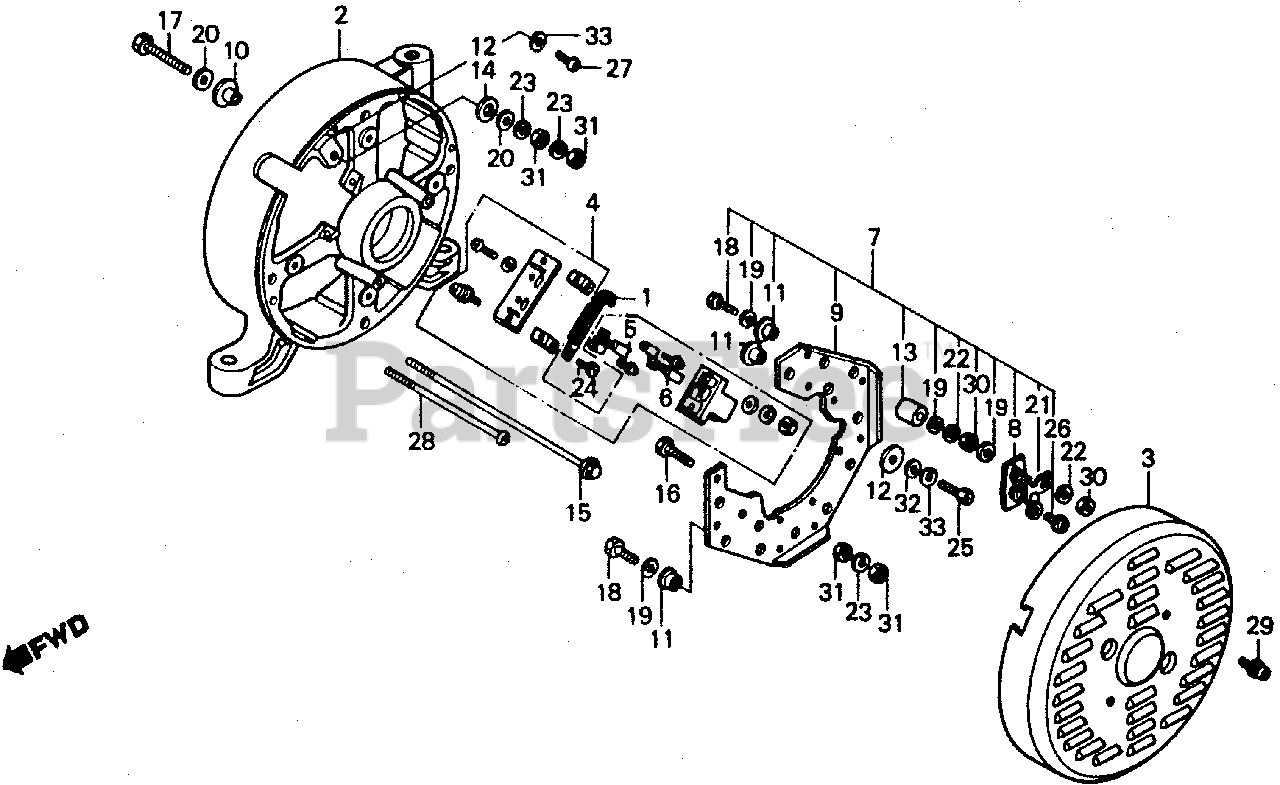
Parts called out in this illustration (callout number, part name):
1	CLAMP B, WIRE
2	HOUSING, RR. *R8* (BRIGHT RED)
3	COVER, ALTERNATOR END *R8* (BRIGHT RED)
4	HOLDER ASSY., BRUSH (NOT AVAILABLE)
5	BRUSH (A) (NOT AVAILABLE)
6	BRUSH (B) (NOT AVAILABLE)
7	DIODE ASSY.
9	PLATE, HEAT SINK (NOT AVAILABLE)
10	BUSH, INSULATING (6MM)
11	BUSH, INSULATING (5MM)
12	WASHER, INSULATING
13	INSULATOR (5MM)
14	WASHER, INSULATING
15	BOLT, HEX. (6X230)
16	BOLT, HEX. (6X14)
17	BOLT, HEX. (6X30)
18	BOLT, HEX. (5X35) (NOT AVAILABLE)
19	WASHER, PLAIN (5MM) (NOT AVAILABLE)
20	WASHER, PLAIN (6MM)
21	WASHER, SPRING (4MM)
22	WASHER, SPRING (5MM)
23	WASHER, SPRING (6MM)
24	BOLT, HEX. (5X10)
25	BOLT, HEX. (5X20)
26	SCREW, PAN (4X8)
27	SCREW, PAN (5X12)
28	SCREW, PAN (5X65)
29	SCREW-WASHER (5X10)
30	NUT, HEX. (5MM)
31	NUT, HEX. (6MM)
32	WASHER, PLAIN (5MM)
33	WASHER, SPRING (5MM)
